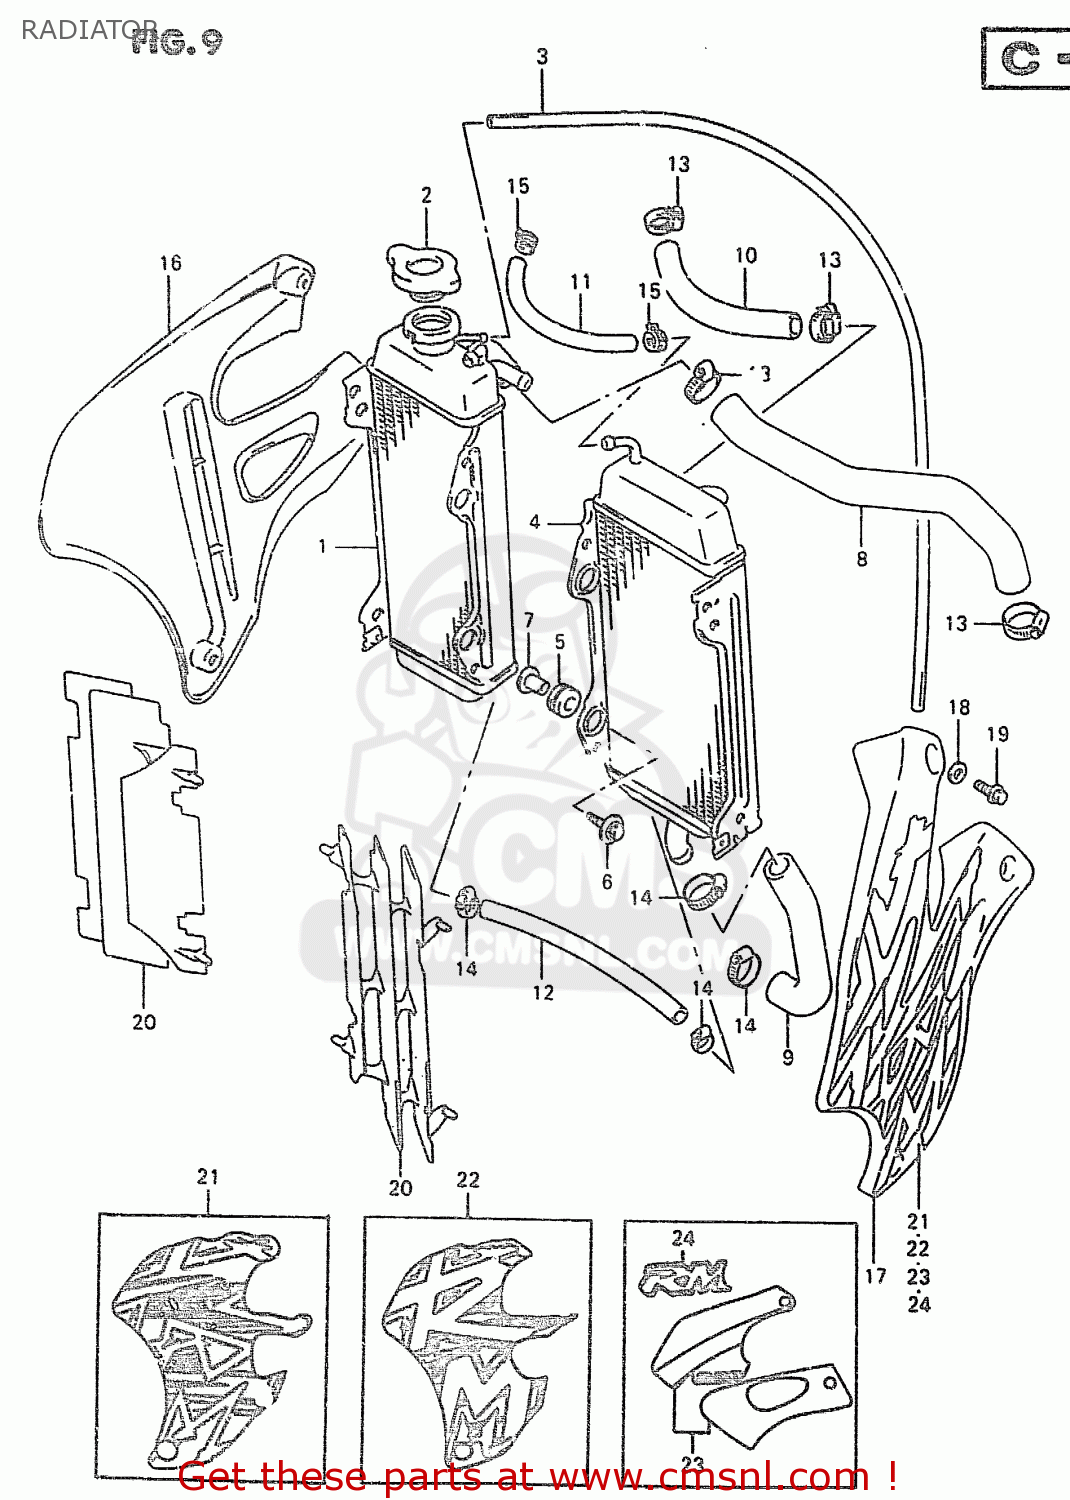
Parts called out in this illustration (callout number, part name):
1	RADIATOR COMP,WATER,RIGHT
2	CAP,RADIATOR
3	HOSE(5X8X2000)
4	RADIATOR,WATER,L
5	CUSHION,RADIATOR LWR
6	BOLT(6X25)
7	SPACER(6.5X10.5X14.1)
8	HOSE,RADIATOR INLET
9	HOSE,RADIATOR OUTLET
10	HOSE,RADIATOR JOINT NO.1
11	HOSE,RADIATOR BYPASS
12	HOSE,RADIATOR JOINT NO.2
13	CLAMP
14	CLAMP
15	CLIP
16	COVER,RADIATOR,R
17	COVER,RDTR,L
18	WASHER
19	BOLT
20	LOUVER,RADIATOR
21	EMBLEM,RADIATOR COVER
22	EMBLEM,RADIATOR COVER,R
23	TAPE SET,RADIATOR COVER
24	EMBLEM,RADIATOR COVER,R
